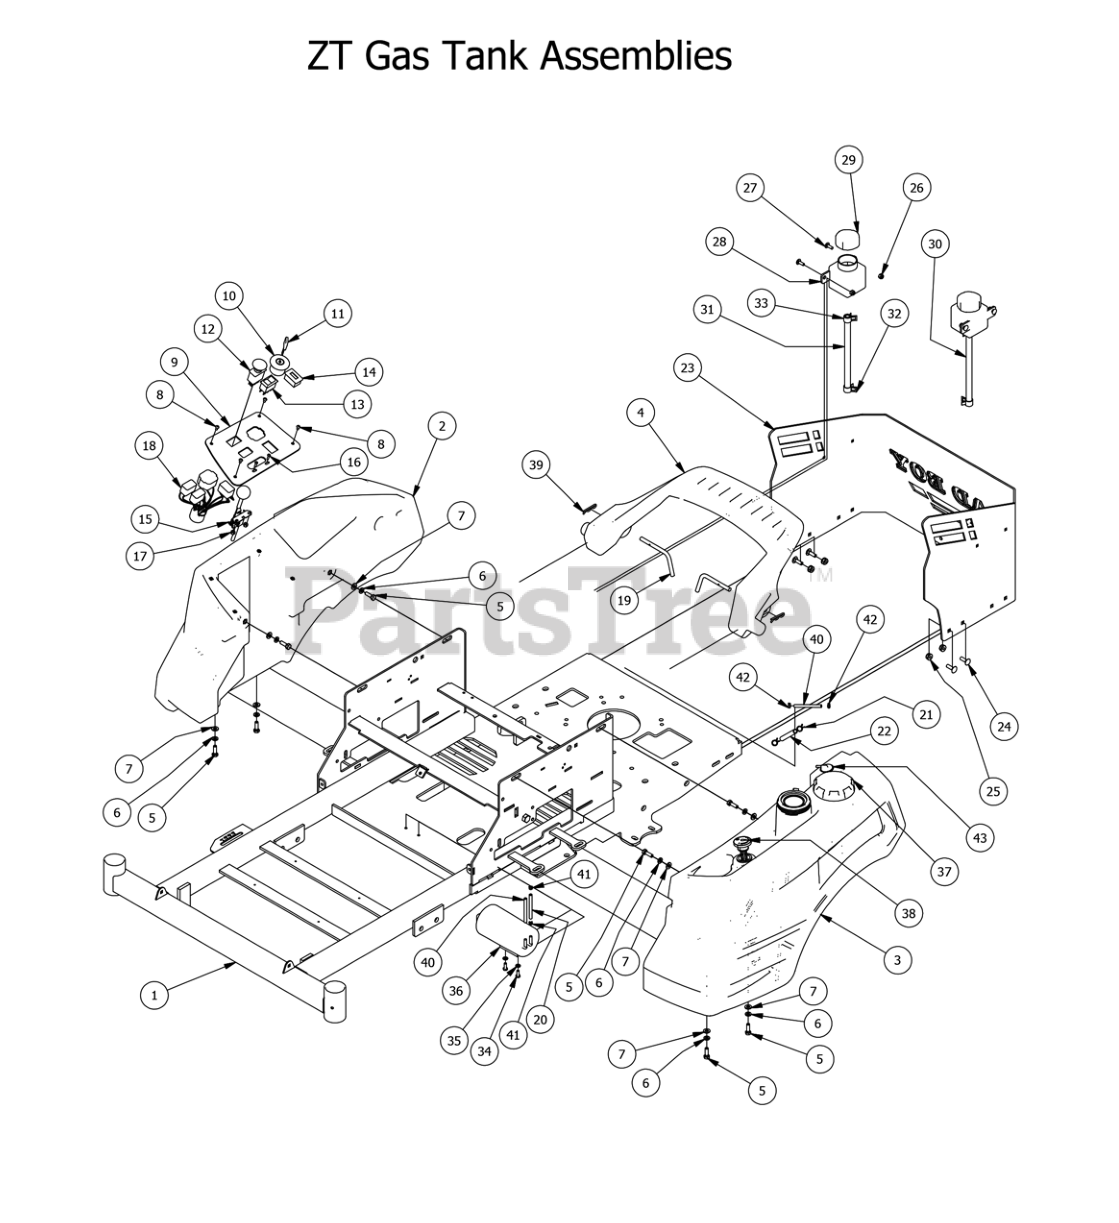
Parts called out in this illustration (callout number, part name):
1	ZT/CZT Frame 2013 Models
2	2014 ZT Right Side Console
3	2014 ZT Left Fuel Tank
4	2014 ZT Spoiler
5	5/16" x 1" Bolt
6	5/16" Lock Washer
7	5/16" Flat Washer
8	10-32 x 3/8" Button Socket Head Bolt
9	2014 ZT Control Panel
10	Ignition Switch
11	Ignition Key
12	PTO Engager
13	Rocker Deck Lift Switch 2011
14	Tachometer
15	Throttle Lever Assembly
16	10-24 X 5/8 BS C/S 18-8 SS
17	10-24 Nylon Insert Locknut
18	Harness-ZT Only-2008 and up
19	Bent Pin-2014 ZT Spoiler
20	3/16 vinyl tubing
21	1/4 fuel clamp
22	1/4" fuel line hose
23	2014 ZT Rear Plate
24	5/16" x 1" Carriage Bolt
25	5/16-18 Nylon Flange Nut
26	1/4" Nylock Nut
27	1/4" x 3/4" Carriage Bolt
28	350ml Expansion Tank-CZT
29	Hydraulic Tank Cap
30	2013 ZT Hydraulic Hose Assembly
31	3/8 clear hose price per foot
32	1/2 Hose Clamp
33	3/8 hose clamp
34	M6-1.0 X 16MM Hex Bolt
35	1/4" Lock Washer
36	Carbon Canister ZT,CZT,Outlaw
38	Fuel Gauge Tanks W/downtube
39	Cotter Ping-ZT Spoiler
40	1/4" vinyl tubing
41	3/16" Vinyl Hose Clamp
42	1/4" vinyl clamp
43	Rollover Valve-White
